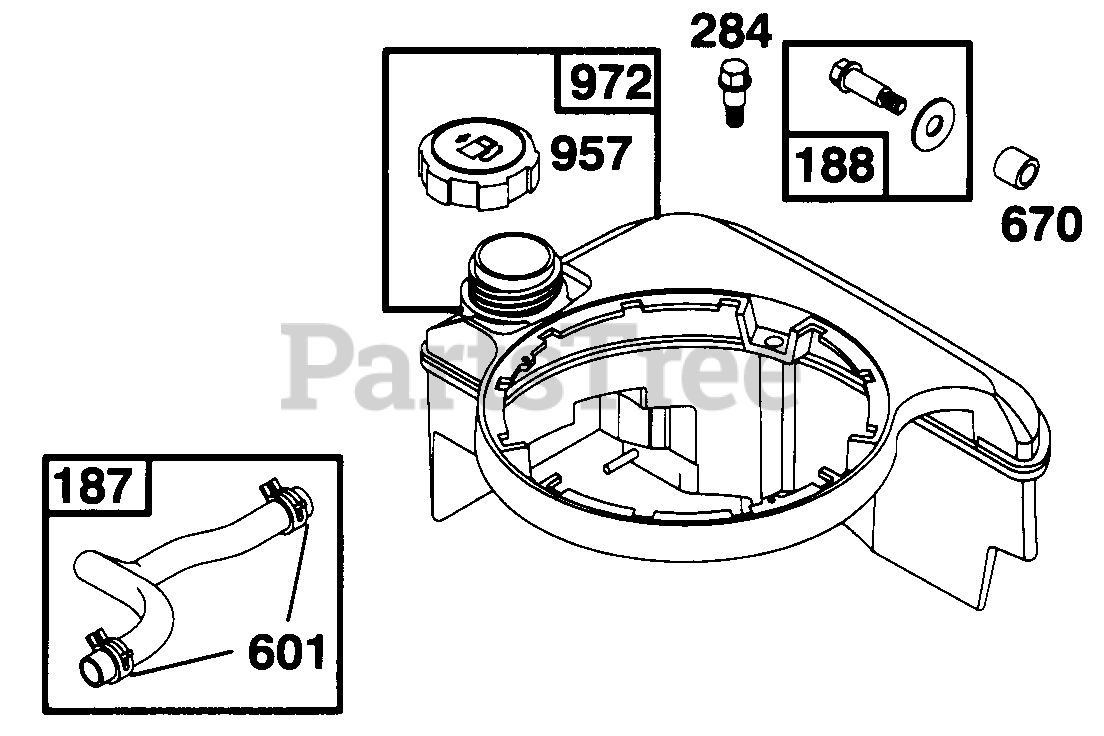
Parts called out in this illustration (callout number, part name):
187	Hose-Fuel
188	Screw-Hex. Head
284	Screw-Hex. Hd.
601	Clamp-Hose
670	Spacer-Fuel Tank
957	Cap-Fuel Tank
972	Tank-Fuel
